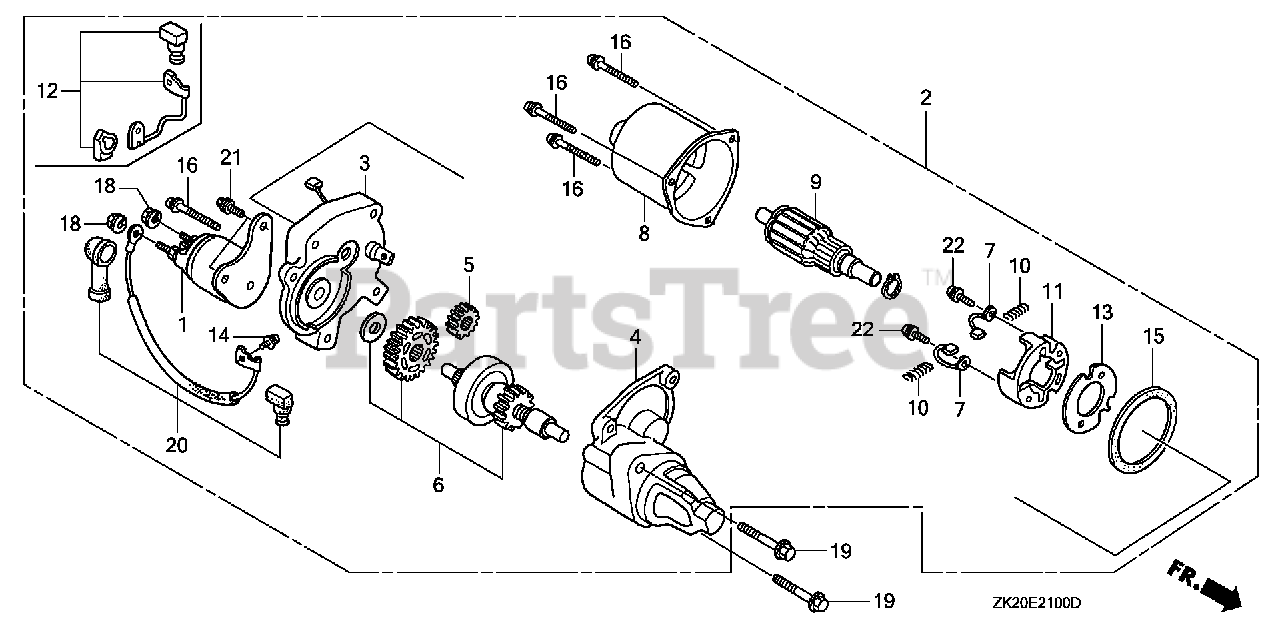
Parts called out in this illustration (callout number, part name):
1	CONTACTOR ASSY.
2	STARTER MOTOR UNIT
3	BRACKET, CENTER
4	BRACKET, FR.
5	GEAR, DRIVE PINION
6	CLUTCH, OVERRUNNING
10	SPRING, BRUSH RETURN
11	HOLDER, BRUSH
14	SCREW-WASHER (4X6)
16	SCREW-WASHER (5X32)
18	NUT-WASHER (6MM)
19	BOLT, FLANGE (8X40)
20	WIRE, WATER COVER
21	BOLT-WASHER (5X14)
22	SCREW-WASHER (4X14)
